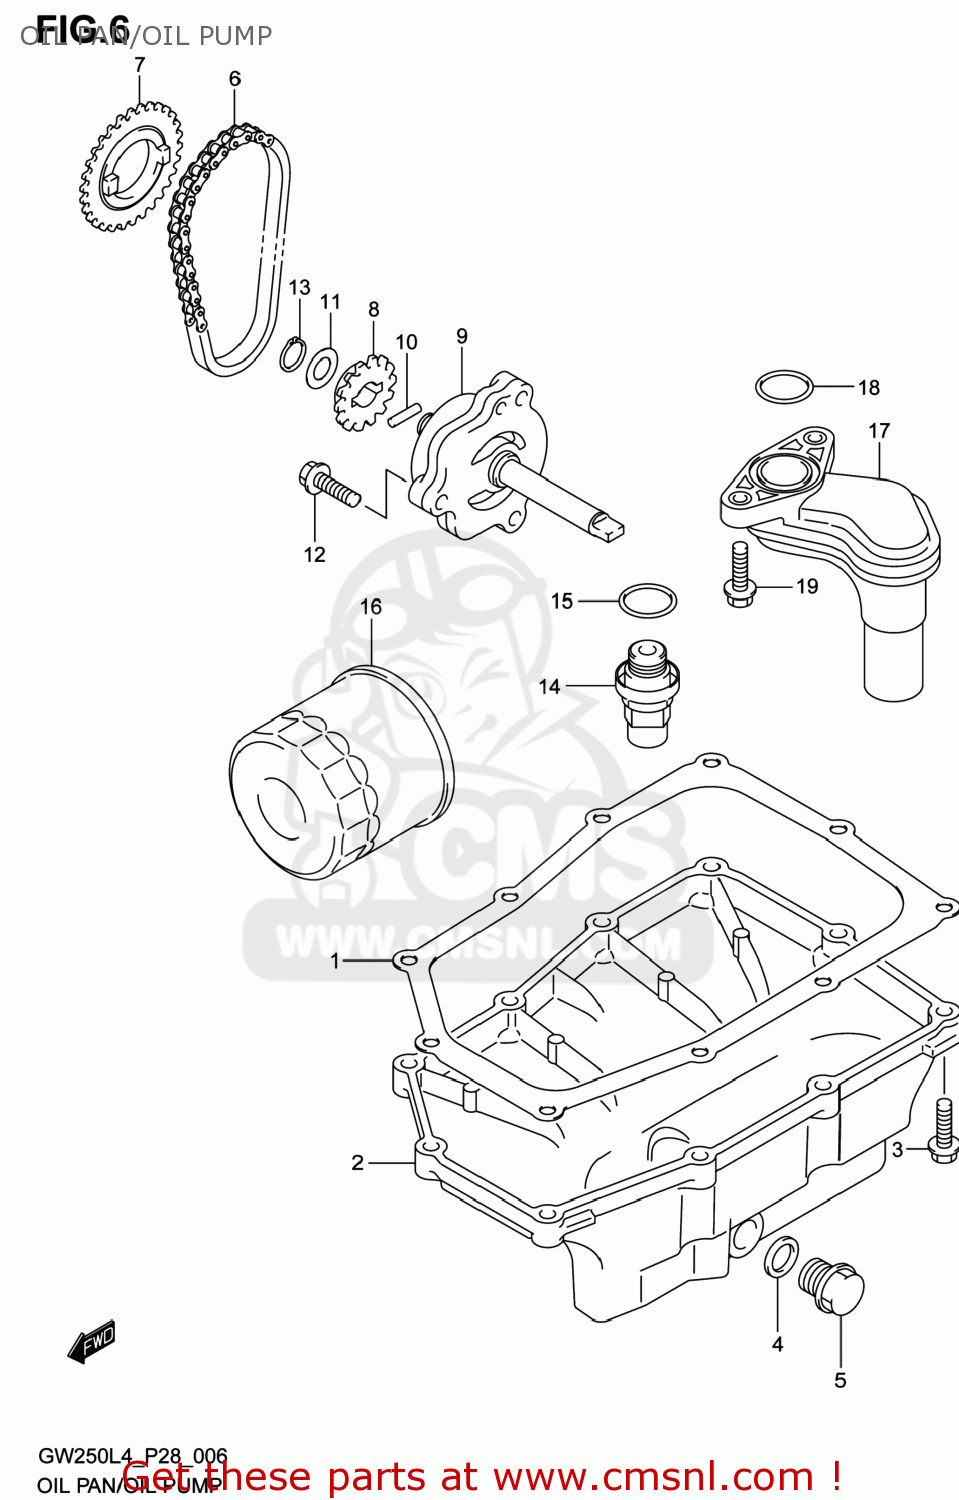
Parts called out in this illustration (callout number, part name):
1	GASKET,OIL PAN(ASB) (NAS)
2	PAN,OIL
3	BOLT
4	GASKET(13.8X18.8X4.8) (NAS)
5	PLUG(14X12)
6	CHAIN,OIL PUMP DRIVE
7	SPROCKET,OIL PUMP DRIVE
8	SPROCKET,OIL PUMP DRIVEN
9	PUMP ASSY,OIL
10	PIN,OIL PUMP
11	WASHER,PUMP DRIVEN GEAR THR
12	BOLT
13	CIRCLIP
14	VALVE ASSY,OIL RELIEF
15	GASKET(16X22X2) (NAS)
16	FILTER ASSY,ENGINE OIL
17	STRAINER,ENGINE OIL
18	O RING(D:2.4,ID22.8)
19	BOLT
